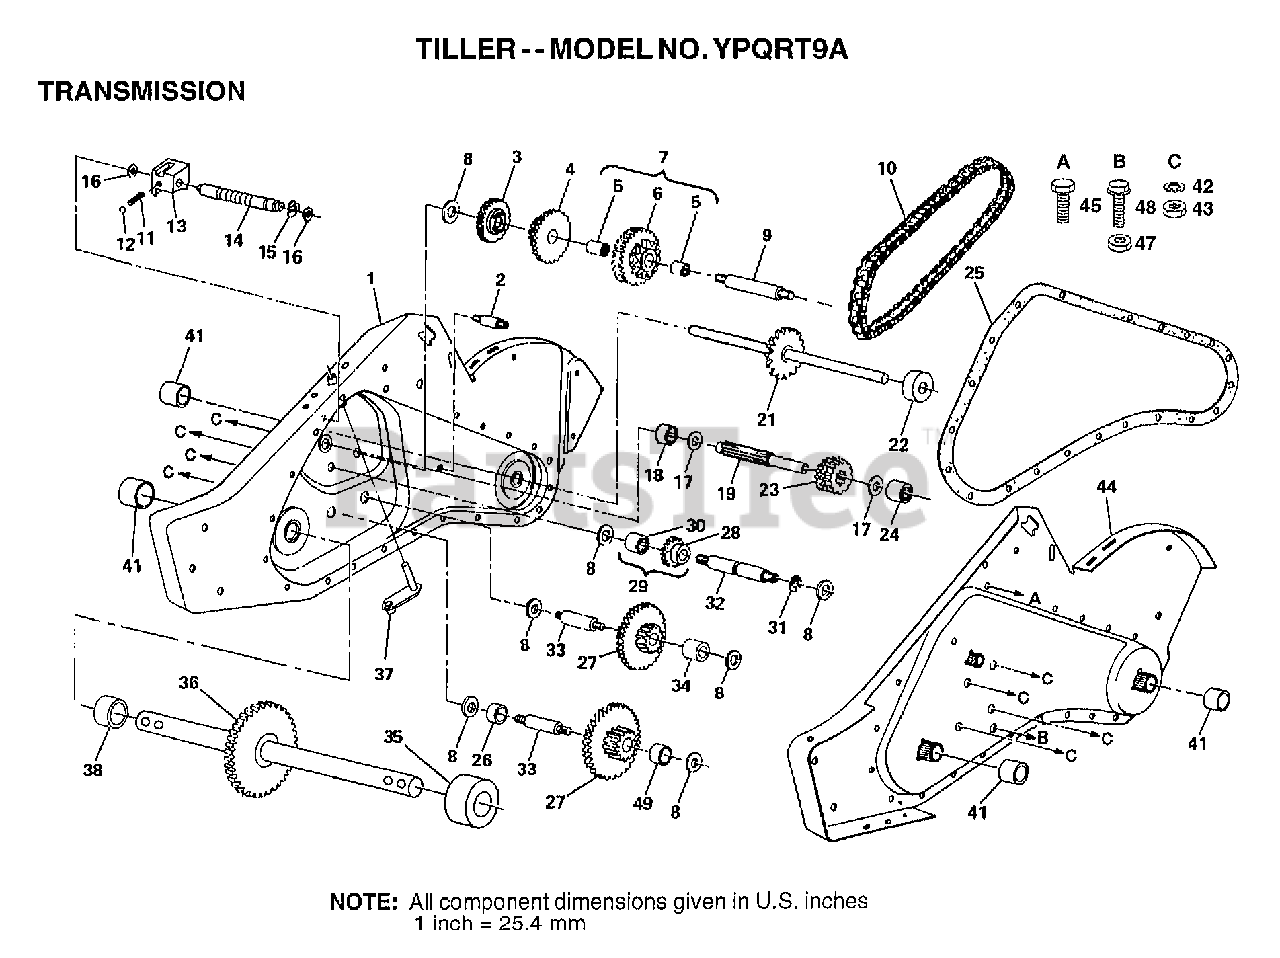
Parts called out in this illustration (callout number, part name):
2	BOLT TI
3	REVERSE GEAR TI
4	CLUSTER GEAR TI
5	"CRT, BEARING"
7	SPROCKET ASSY TI
8	WASHER
9	REDUCTION SHFT TI
10	CHAIN TI
11	SPRING-SHIFT CRT
13	SHIFT FORK TI
14	SHIFT SHAFT TI
15	KLIP RING
16	WASHER SEAL
17	"T, BEARING"
18	"TI, BEARING"
19	SHAFT INPUT
21	SHAFT TINE CRT
22	SPACER CRT
23	INPUT PINION TI
24	NEEDLE BRNG LT
25	GASKET.GEARCASE
26	SPACER CRT
27	GEAR CLUSTER CRT
28	REVERSE GEAR TI
29	GEAR ASSY TI
30	NEEDLE BEARING TI
31	KLIP RING
32	REVERSE SHAFT TI
33	SHAFT CRT
34	SPACER CRT
35	SPACER CRT
36	SHAFT ASSY CRT
37	BRACKET ASM SHIFT
38	SPACER CRT
41	SEAL ASM-OIL
42	LOCKWASHER
43	NUT.ASF.HEX.7/16
44	"GEARCASE ASSY,LH"
45	SCREW 5/16-18X5/8
47	NUT.HEX.5/16-18
48	BOLT TI
49	SPACER CRT
